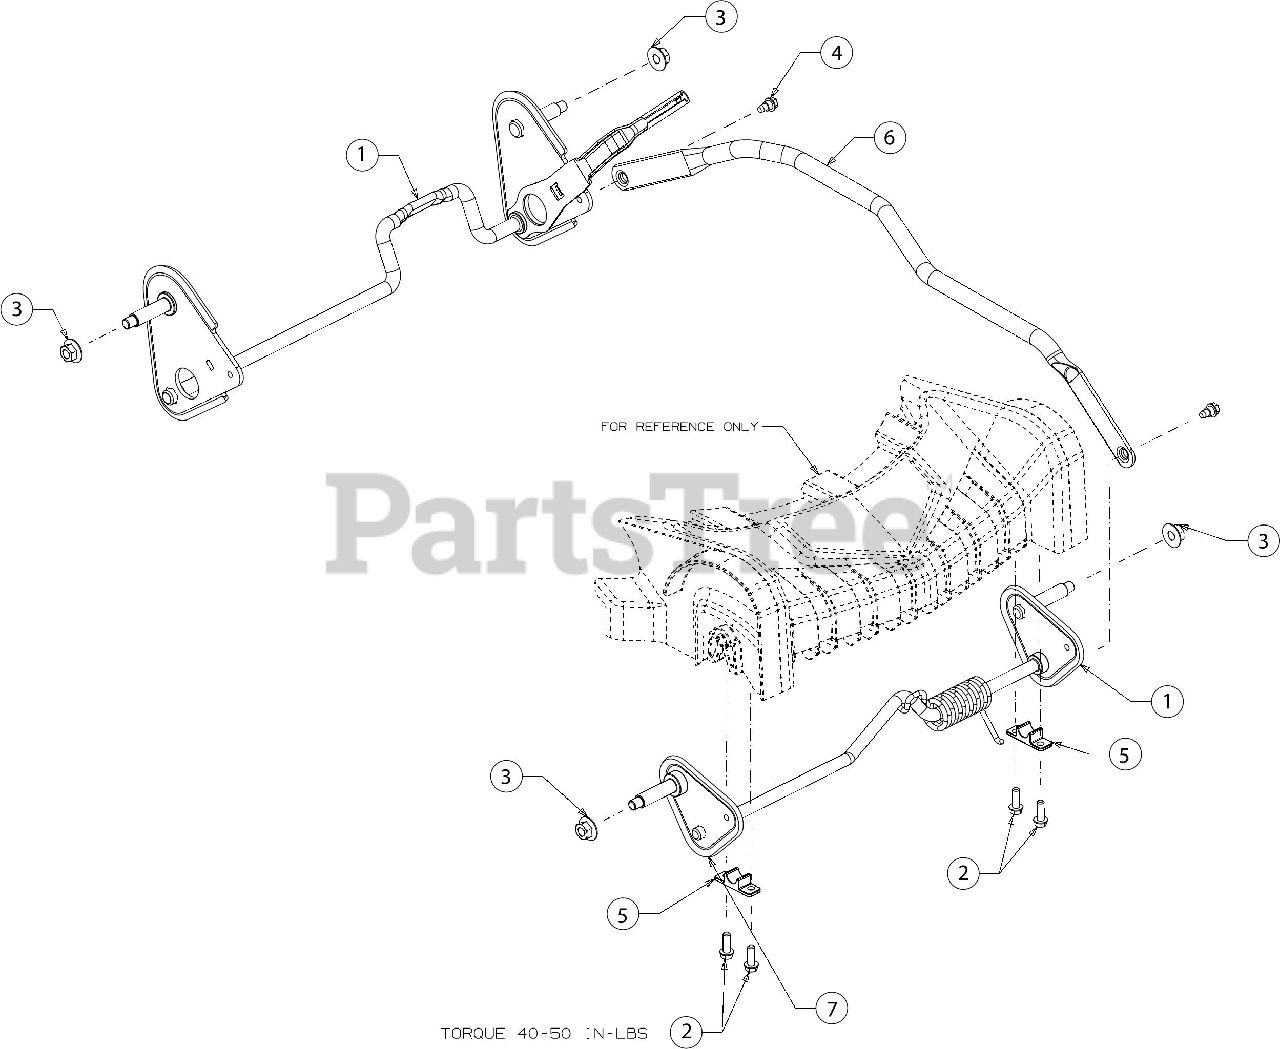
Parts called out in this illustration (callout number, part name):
1	HEIGHT AXLE ASSEMBLY
2	SCREW 1/4-15 X .750
3	FLANGE LOCK NUT
4	SHOULDER SCREW 1/4-20 X .50
5	BLOCK BUSHING
7	FRONT AXLE ASSEMBLY
